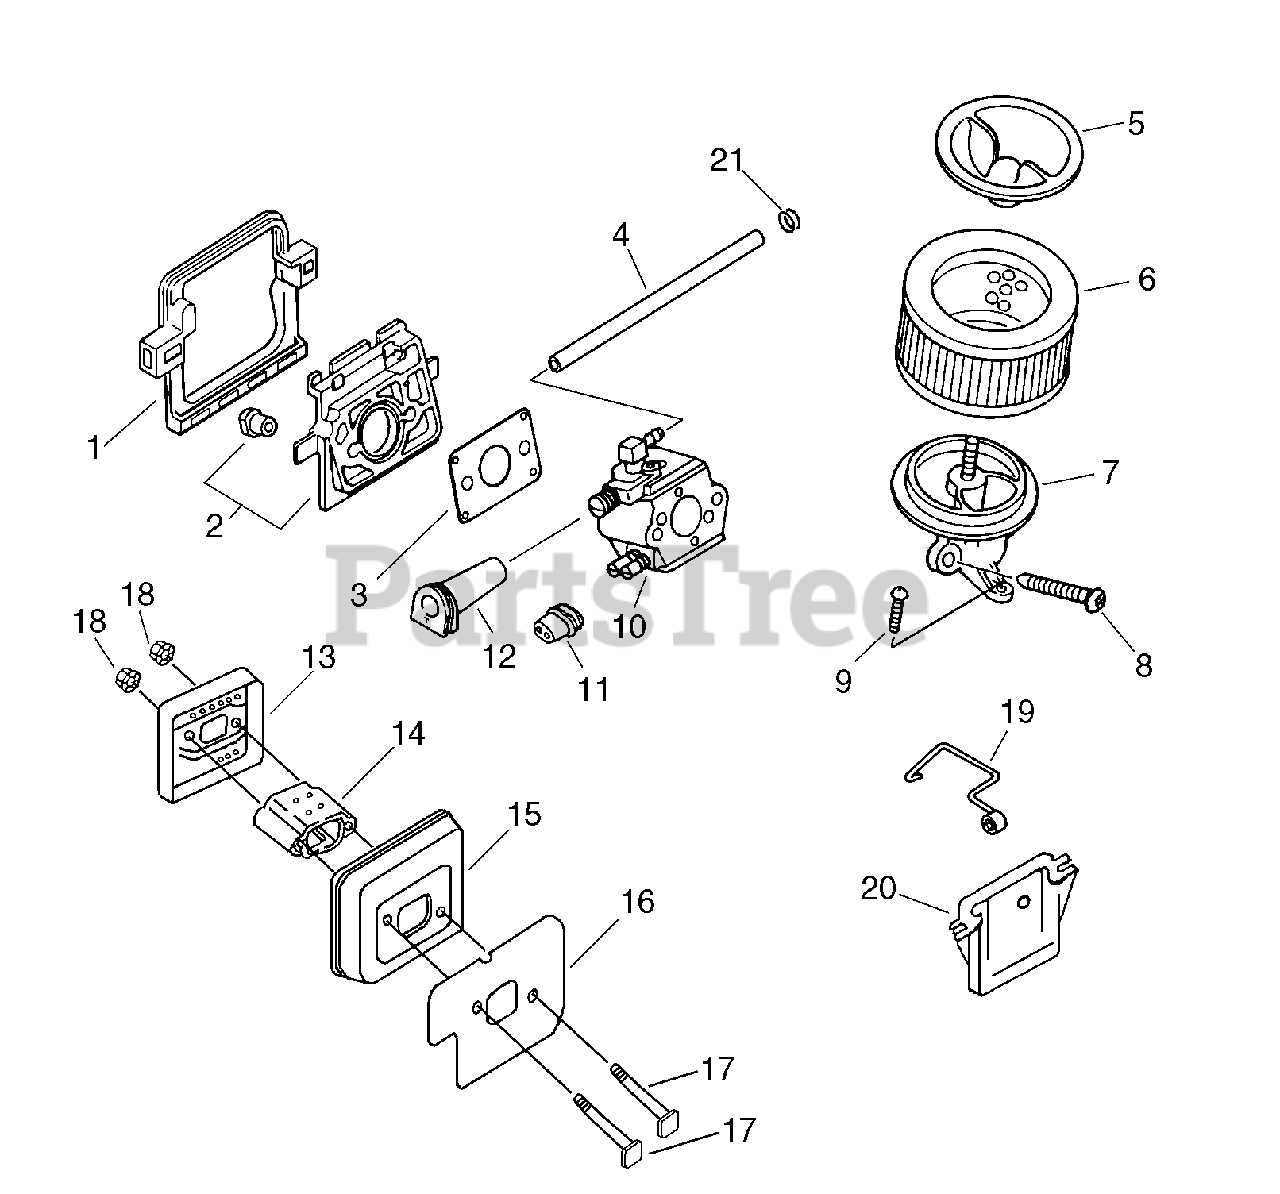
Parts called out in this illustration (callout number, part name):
1	CUSHION
2	INSULATOR KIT
3	GASKET, INTAKE
4	PIPE - 3X6X105 -- BLACK
5	COVER, AIR FILTER
6	FILTER, AIR
7	ADAPTOR, INTAKE
8	SCREW - 5X50
9	SCREW - 5X16 -- TAPPING
10	CARBURETOR
13	LID, MUFFLER
14	PLATE, MUFFLER
16	GASKET, EXHAUST
18	NUT - 5 -- FLANGE
19	ROD, THROTTLE
20	GUIDE, THROTTLE
21	CLIP - 6
